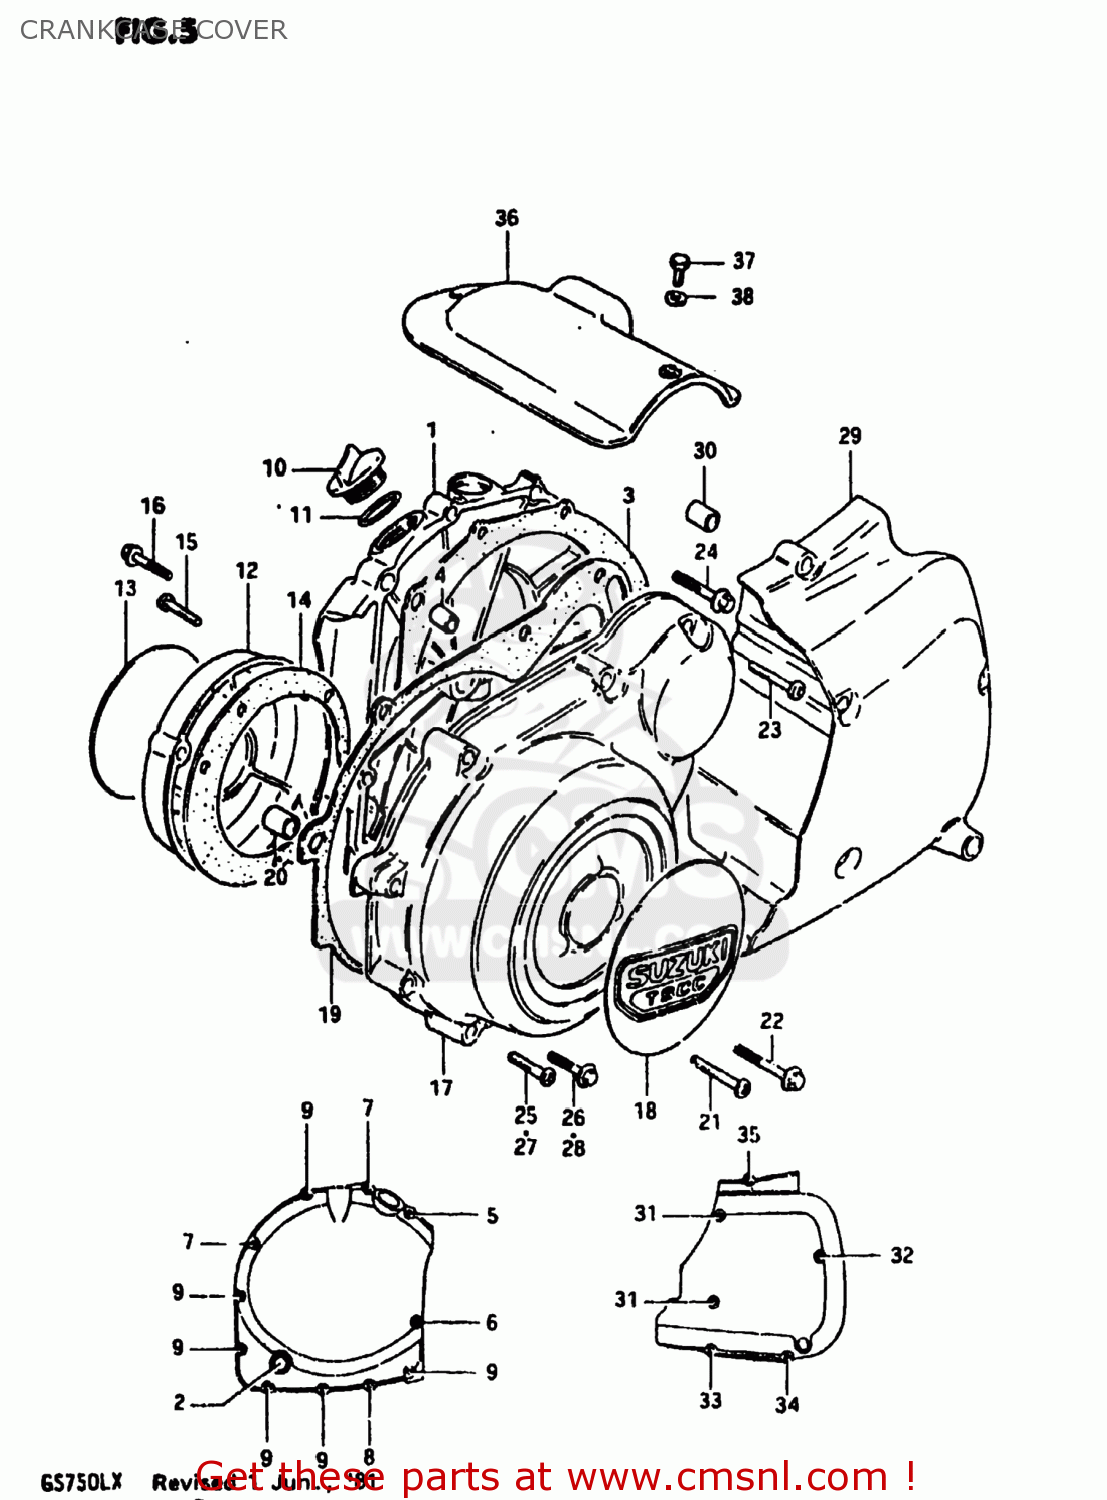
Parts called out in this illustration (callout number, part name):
1	COVER,CLUTCH
2	LENS,OIL LEVEL CHECK
3	GASKET,CLUTCH COVER (MCA)
4	PIN
5	SCREW
6	BOLT (6X35)
7	SCREW 6X30
8	BOLT
9	SCREW
10	CAP
11	O RING(D:2.2,ID:32)
12	COVER,CONTACT BREAKER
13	EMBLEM
14	GASKET,CONTACT BREAKER COVER (NAS)
15	SCREW
16	BOLT (5*30)
17	COVER
18	EMBLEM,MAGNETO COVER
19	GASKET,MAGNETO COVER (MCA)
20	PIN
21	SCREW (6X45)
22	BOLT
23	SCREW
24	BOLT (6X40)
25	SCREW (6X35)
26	BOLT (6X35)
27	SCREW 6X30
28	BOLT (6X30)
29	COVER,SPROCKET
30	PIN
31	BOLT 6X95
32	SCREW 6X85
33	SCREW 6X70
34	SCREW
35	SCREW 6X30
36	COVER,STARTER MOTOR
37	BOLT
38	WASHER
